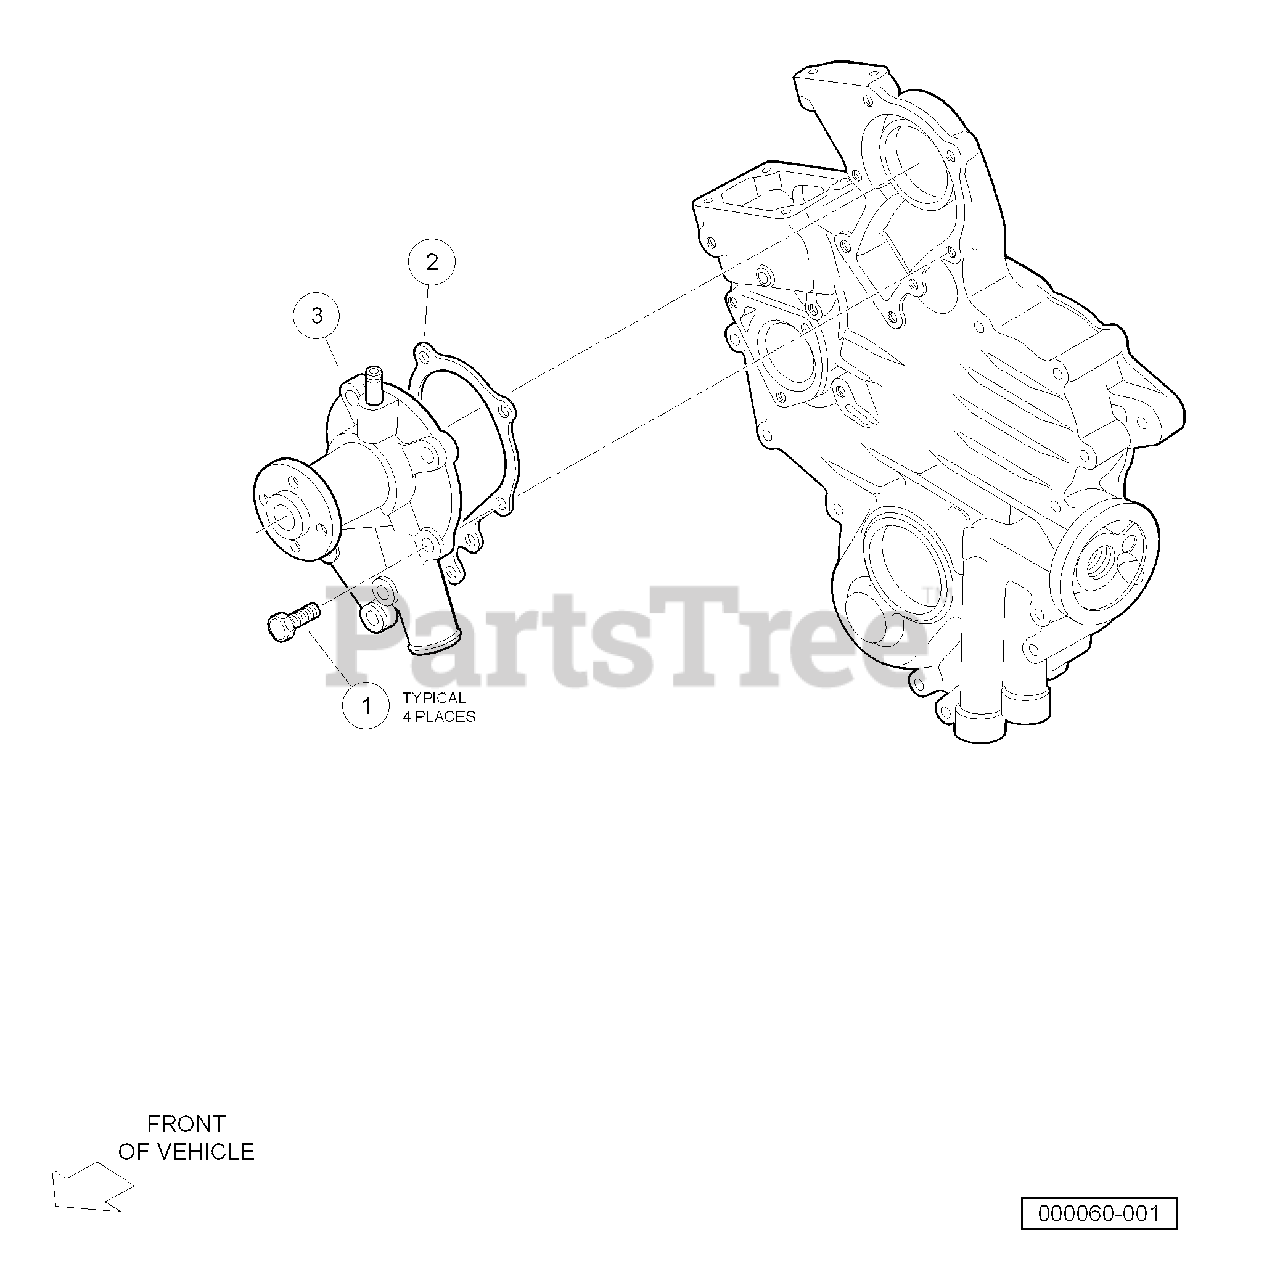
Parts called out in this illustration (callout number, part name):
1	Bolt, M6 X 1 X 22
2	Gasket, Water Pump, D722
3	Water Pump Assembly
